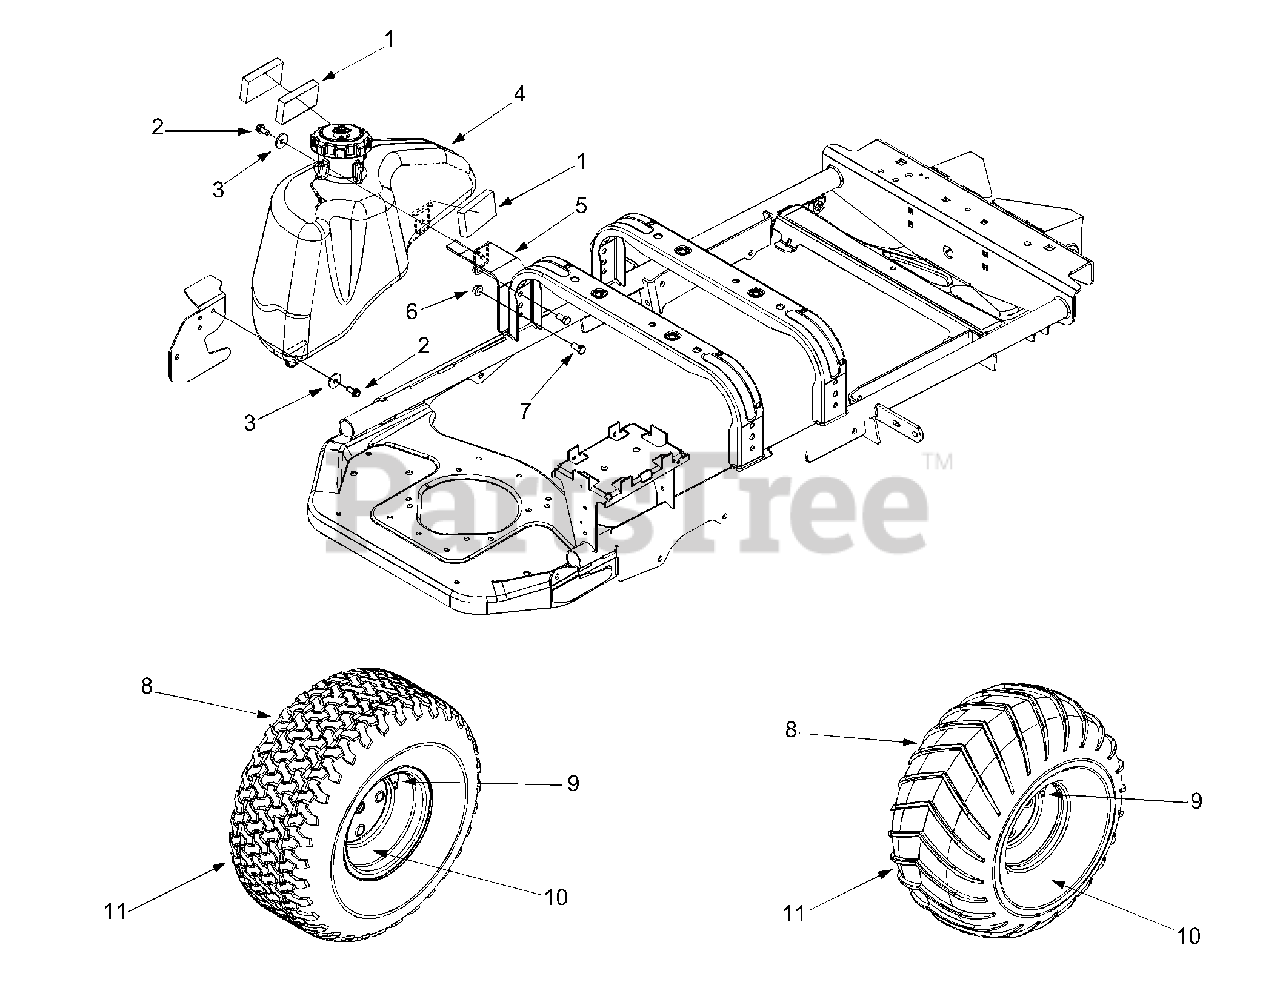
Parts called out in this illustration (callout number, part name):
1	Foam 2.04 x 3.50 x .62
2	Hex Washer Screw 5/16-18 x .75
3	Flat Washer .344 ID x 1.125 OD
4	Tank Assembly 4.0 Gallon
7	Hex Cap Screw 3/8-16 x .75
10	Tubeless Air Valve
